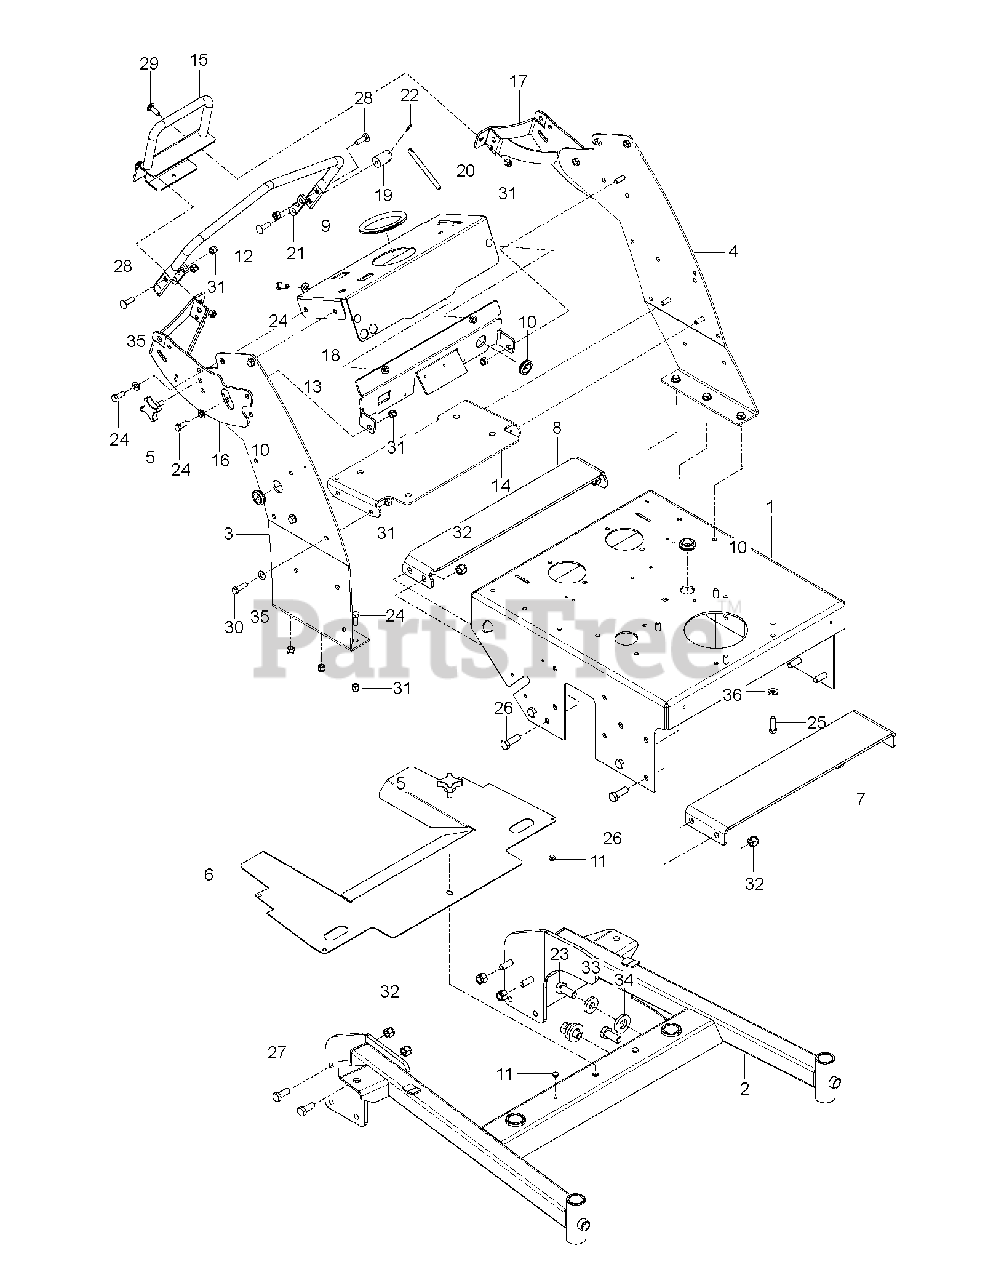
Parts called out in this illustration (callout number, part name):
1	FRAME ASSY FRAME HYDRO W/ DECA
2	DECK FRAME WLDT DECK FRAME 48
3	BODY ASSY WLDMT, RH UPRIGHT TO
4	BODY ASSY WLDT, LH UPRIGNT TOW
5	KNOB KNOB, 3/8 -16 X .75
6	SHIELD BELT 48" HYDRO WALK HSQ
7	PLATE, ENGINE BED FRONT ORG
8	PLATE ENGINE BED REAR 52/48 39
9	TRIM RUBBER EDGE 12" 170900
10	GROMMET GROMMET, RUB:.88ID X 1
11	BUMPER BUMPER GROMMET .125 X .
12	SUPPORT HANDLE 3730748
13	BRACE HANDLE BRACE WLDT 419064
15	BAR REVERSE BAR WMT 4292848
16	MOUNT RH CONTROL MOUNT WMT 429
17	MOUNT LH CONTROL MOUNT WMT 429
18	CONSOLE HUSQ CONSOLE W/ DECALS
19	BUSHING BUSHING, 1.03 X 1.50 X
20	LEVER LOCK LEVER D13309
21	SHIM 5 DEG SPEED BAR (HUSQR) 3
22	Spring Pin, 5/32 X 1
23	BOLT BOLT, HEX 5/8-11 1.5" GR8
24	BOLT BOLT HEX .38-16 X 1.00 GR
25	BOLT BOLT HEX .38-16 X 1.25 GR
27	BOLT BOLT HEX .50-13 X 1.25 GR
28	BOLT BOLT 3/8-16X1-1/4 RD HD A
29	BOLT BOLT RDHDSHSQNK .38-16 X
30	BOLT BOLT 3/8-16X1-1/4 HEX HEA
31	NUT NUT, 3/8-16 NYLON LOCK ARI
32	SERVICE PARTS SYSTEM NUT-LK-NY
33	WASHER WASHER, FL-STL .630 X 1
34	SERVICE PARTS SYSTEM WASHER,
35	WASHER WASHER, FL-STL .406 X .
36	WASHER WASHER, 3/8" SPRING DIS
